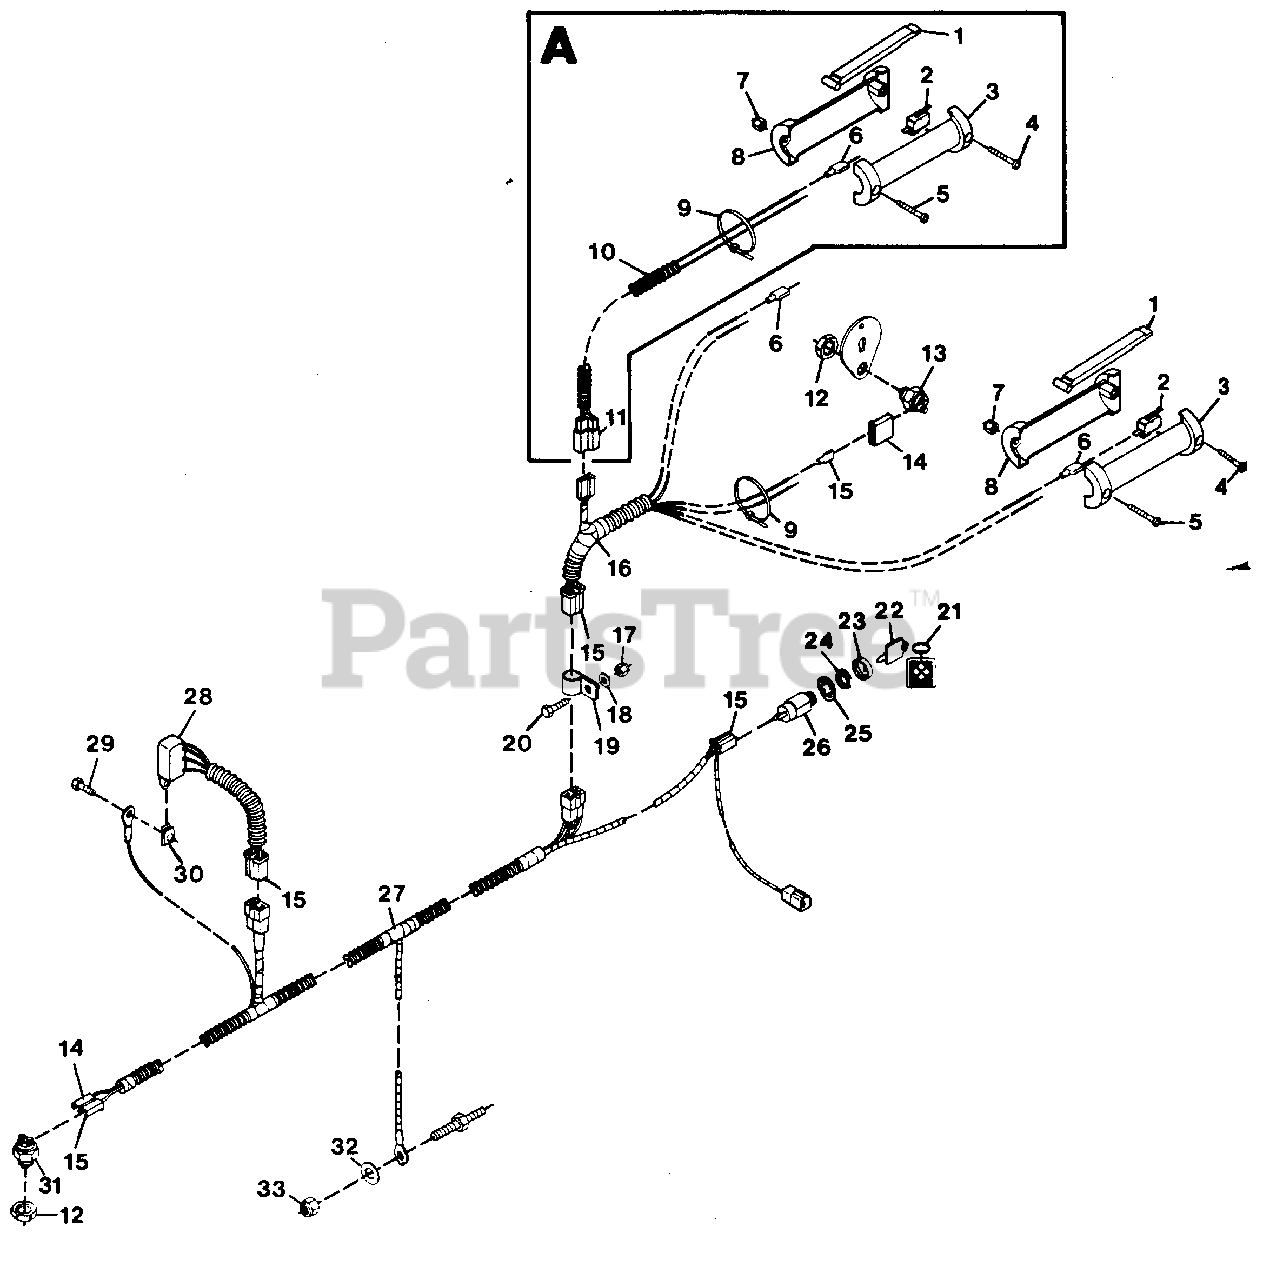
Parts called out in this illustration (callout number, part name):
1	LEVER
2	SWITCH
3	HANDLE, L.H.
4	SCREW, MACH. 10-24X.75 PHD
5	SCREW, MACH. 10-24X1.50 PHDCR
6	TERMINAL, FEMALE
7	NUT, LOCK 10-24
8	HANDLE, R.H.
9	TIE WRAP, BLACK
10	HARNESS, STEERING BRAKE
11	CONNECTOR
12	NUT, STAMPED 9/16-18
13	SWITCH, NEUTRAL START
14	EYELET TERMINAL
15	TERMINAL
16	HARNESS, WIRING HANDLEBAR
17	NUT, LOCK 1/4-20
18	WASHER, FLAT .281X.625X.065
19	CLAMP, NYLON
20	BOLT, HEX 1/4-20X.75
21	CHAIN, KEY
22	KEY, IGNITION SWITCH
23	BOOT, FOR 9/16 SWITCH
24	NUT, 5/8-32 FOR SWITCH
25	WASHER, LOCK 5/8 INT. TOOTH
26	SWITCH
27	HARNESS, WIRING
28	MODULE, INTERLOCK RECOIL
29	BOLT, HEX 1/4-20X.625
30	NUT, SPEED 1/4-20
31	SWITCH, INTERLOCK
32	WASHER, FLAT .469X.938X.065
33	NUT, LOCK 3/8-16
